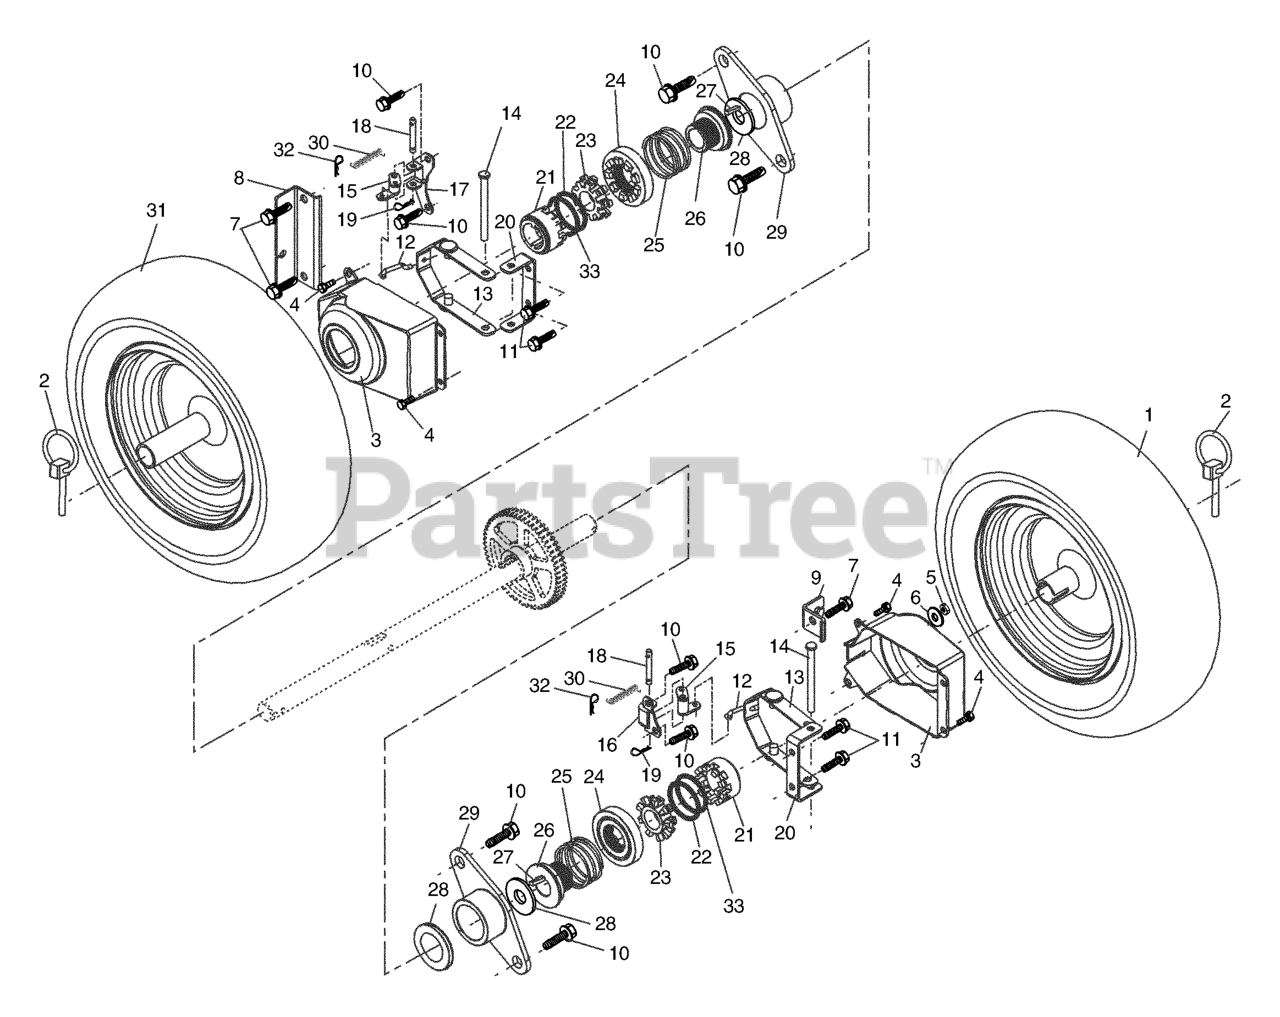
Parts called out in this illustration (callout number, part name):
1	WHEEL ASSY, 16" PWR STR LH
2	PIN KLIK, 1/4
3	COVER, POWER STEERING
4	SCREW, HEX HEAD, TAPPING
5	NUT.71038.31-18.HEX.NYLOCK
6	WASHER.20X8.5
7	Screw, Hex Head 3/8-16 x 1
8	BRACKET, STEERING CABLE RH
9	BRACKET, STEERING CABLE LH
11	Screw, Hex Head 5/16-18 x 1/2
12	LINK
13	YOKE, STEERING
14	PIN, STEERING LEVER
15	BELLCRANK ASSM.
16	BRACKET ASS. LH STEERING
17	BRACKET ASSM RH STEERING
18	PIN, STEERING BELLCRANK
19	RETAINER CLIP PM
20	BRACKET.STEER.PNT.BLACK
21	DRIVER, WHEEL
22	RING, WIRE RETAINER
23	LOBE, WHEEL
24	SLIDE.CLUTCH.SPLINED
25	SPRING, CLUTCH SLIDE
26	LOBE.AXLE.SPLINED
27	KEY
28	WASHER TRUST 1"
29	BEARING, AXLE
30	SPRING
31	WHEEL ASSY, 16" PWR STRG RH
32	RETAINER CLIP
